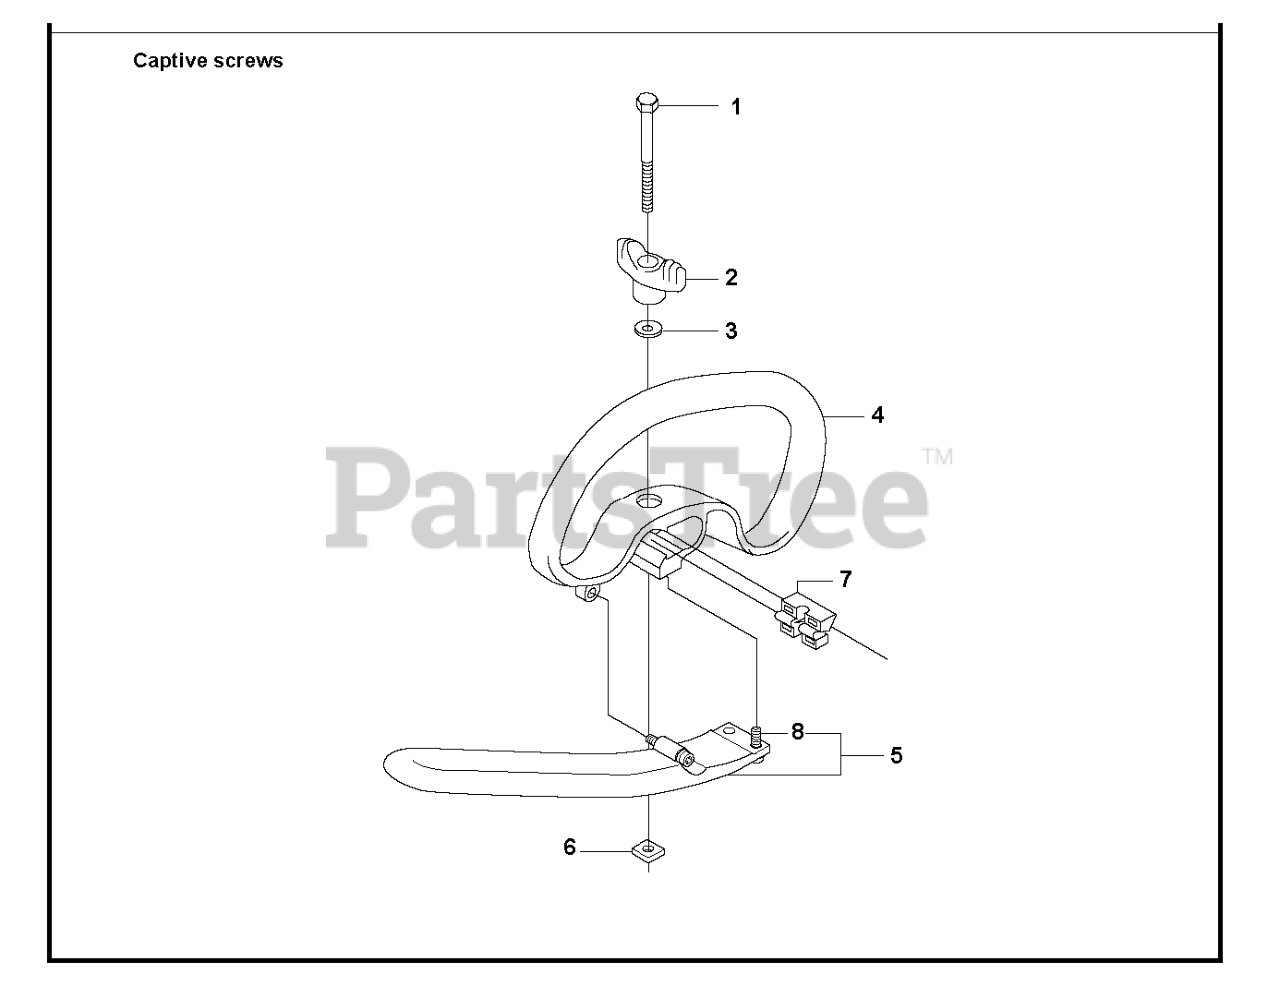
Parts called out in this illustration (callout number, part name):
1	SCREW M6X50
1	SCREW
2	KNOB
3	WASHER
4	HANDLE.LOOP
5	HANDLE EXTENSION
8	SCREW IHSCFTO
